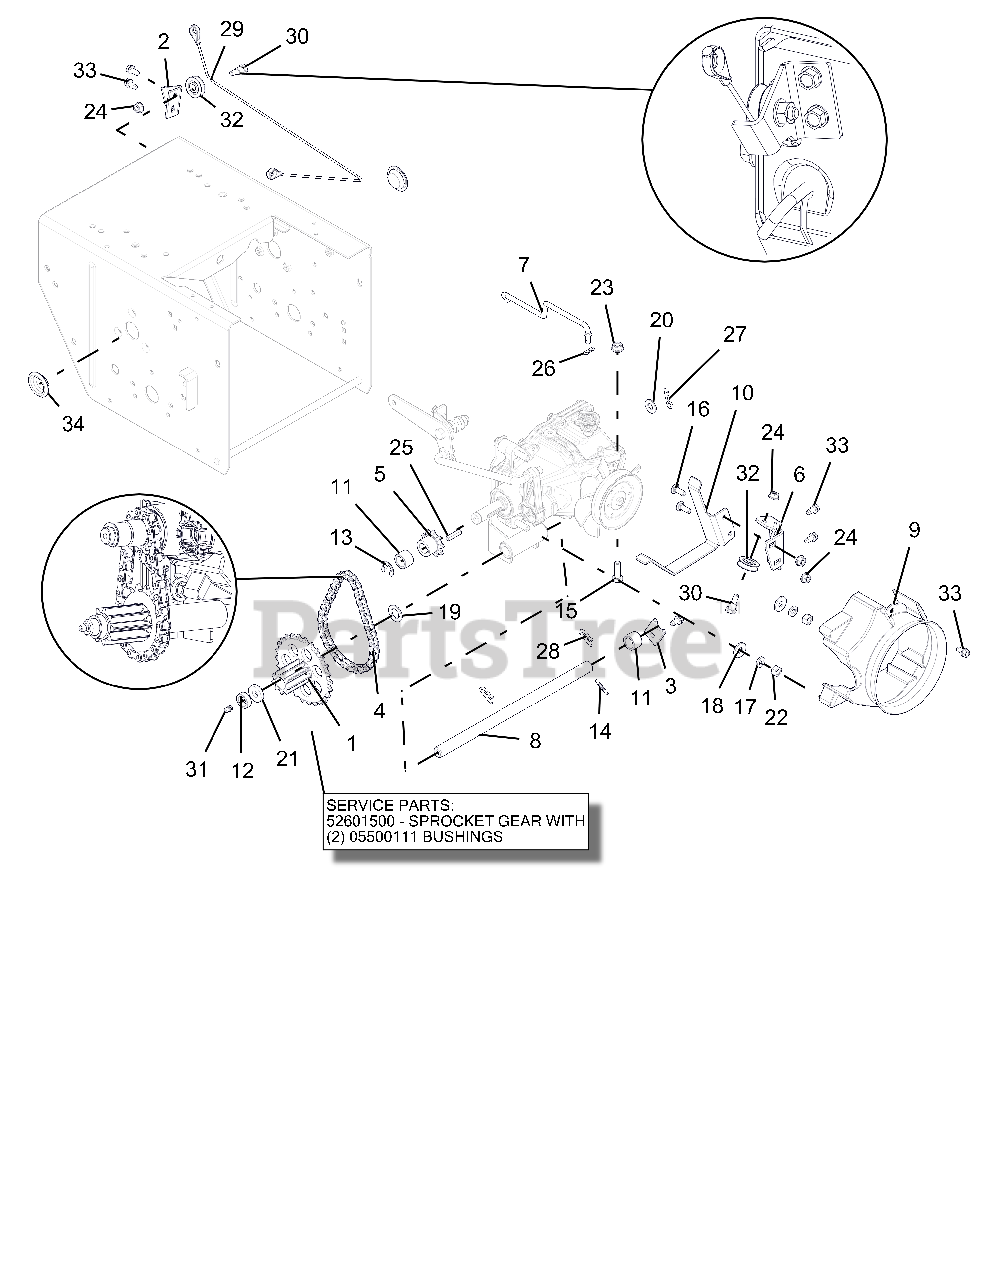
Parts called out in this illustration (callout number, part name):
1	PINION & SPROCKET
1	PINION & SPROCKET W/BUSHINGS
1	BSHG-FLG .625X.750X.500X.875
2	BRACKET, CABLE PULLEY
3	TAB, ANTI ROTATION
4	CHAIN - #41, 32 PITCHES
5	SPROCKET, PINION 9T W/KEY
6	BRACKET, CLUTCH CABLE
7	ROD, HYDRO BYPASS
8	SHAFT, PINION - HARDENED
9	SHROUD, HYDROGEAR RT-310
10	FINGER, BELT - FLAT
11	SPACER, .635X.880X.611
12	BSHG-SLV, .635X.880X.305
13	RG-RTNG-EXT .625X.042
14	@PIN-GRV .125X1.00 TP E ALLOY
15	@BLT-HEX .31-18X1.00 GR5 YWZC
16	@BLT-RDHDSQNK .25-20X.75 G5YZ
17	WSHR-LK .312X.097 HVY YWZC
18	@WSHR-FL-STL.38X.875X.083 YWZC
19	WSHR-FL-STL .630X1.005X.062 YZ
20	@WSHR-FL-STL.406X.812X.065 YWZ
21	WSHR-FL-STL .406X1.00X.188 YWZ
22	@NUT-HEX .31-18 YWZC
23	@NUT-LK-TOP-FLG .31-18 YWZC
24	@NUT-LK-TOP-FLG .25-20 YWZC
25	KEY-SQ .188X1.0X.188 SAE 8630
26	PIN-HAIR INT .06X.18X.77
27	PIN-HAIR INT .08X.18X1.18 YWZC
28	PIN, SPRING CLIP
29	CABLE, TRACTION, HYDRO PRO
30	BOLT, SHLDR-.375X.375X.25-20
31	ZERK,FITTING .25X.125 DRIVE IN
32	PULLEY, CABLE
33	SCR-TAP .25-20X.50 HWH TR YWZ
34	PLUG, HOLE - 1.125"
